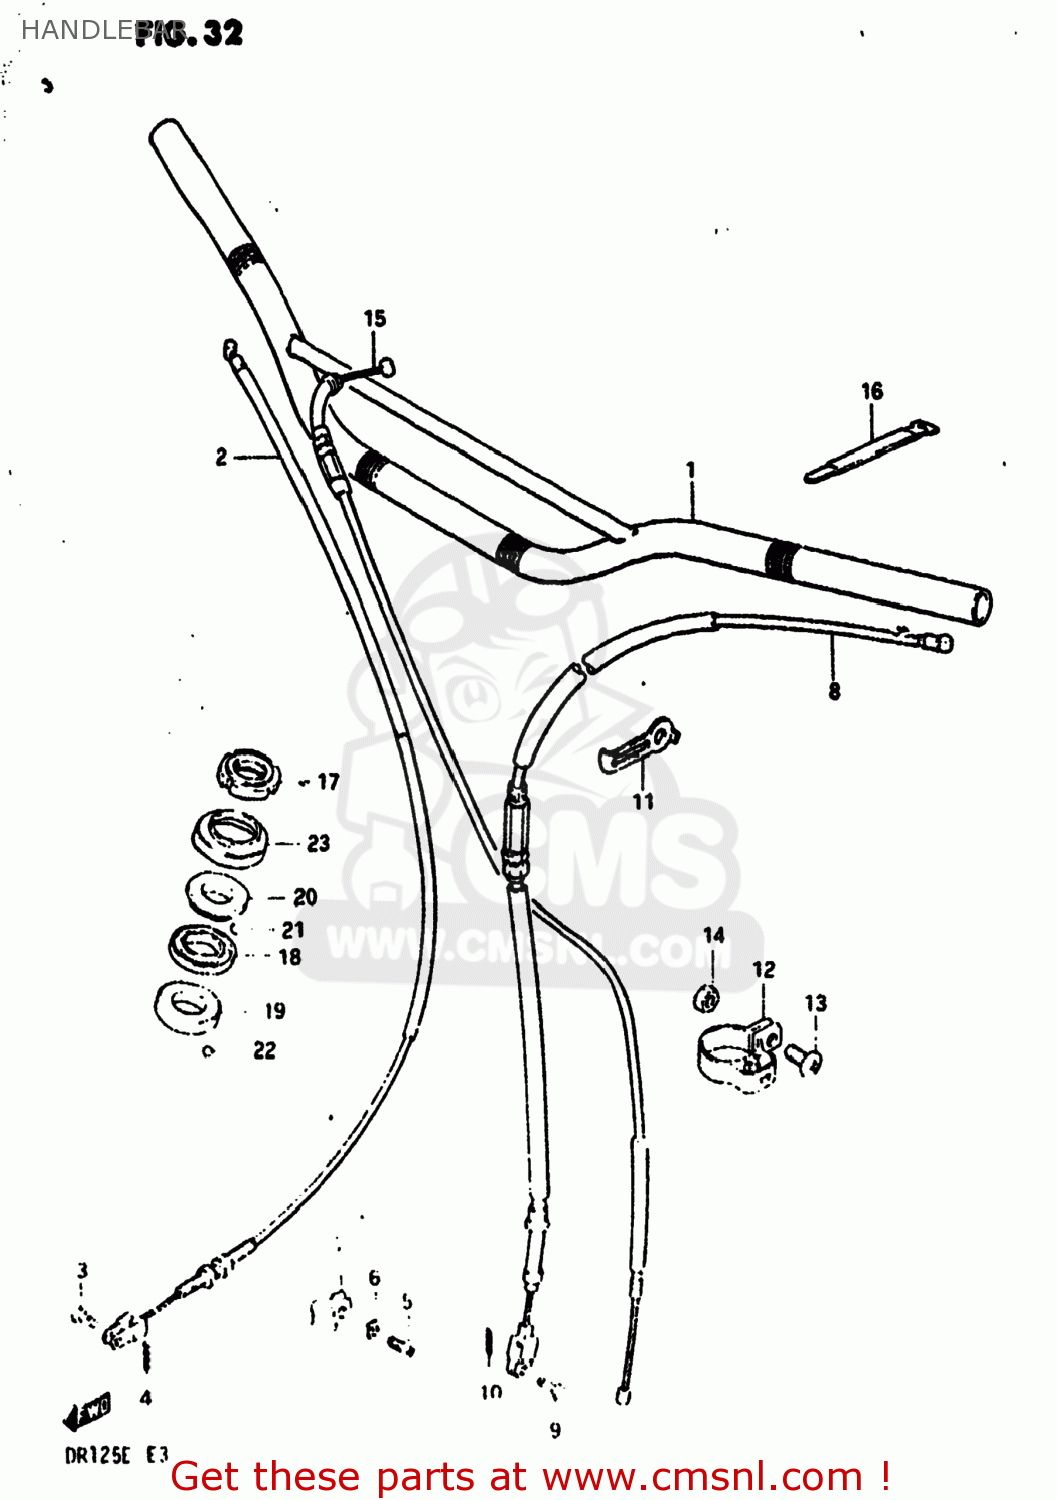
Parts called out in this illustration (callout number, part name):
1	HANDLEBAR
2	CABLE,FRONT BRAKE
3	PIN(L:17.5)
4	PIN
5	SCREW 6X12
6	LOCK WASHER
7	CLAMP,FR BRAKE CABLE
8	CABLE ASSY,CLUTCH
9	PIN(L:15)
10	PIN
11	CLAMP,CABLE
12	CLAMP,CABLE
13	SCREW
14	NUT
15	CABLE ASSY,THROTTLE
16	CLAMP
17	NUT,STEERING STEM(25X44X10)
18	RACE,STEERING INNER UPR
19	LACE,STEERING INNER LWR
20	RACE,STEERING OUTER UPR
21	BALL
22	BALL
23	DUST SEAL,STEERING UPR
